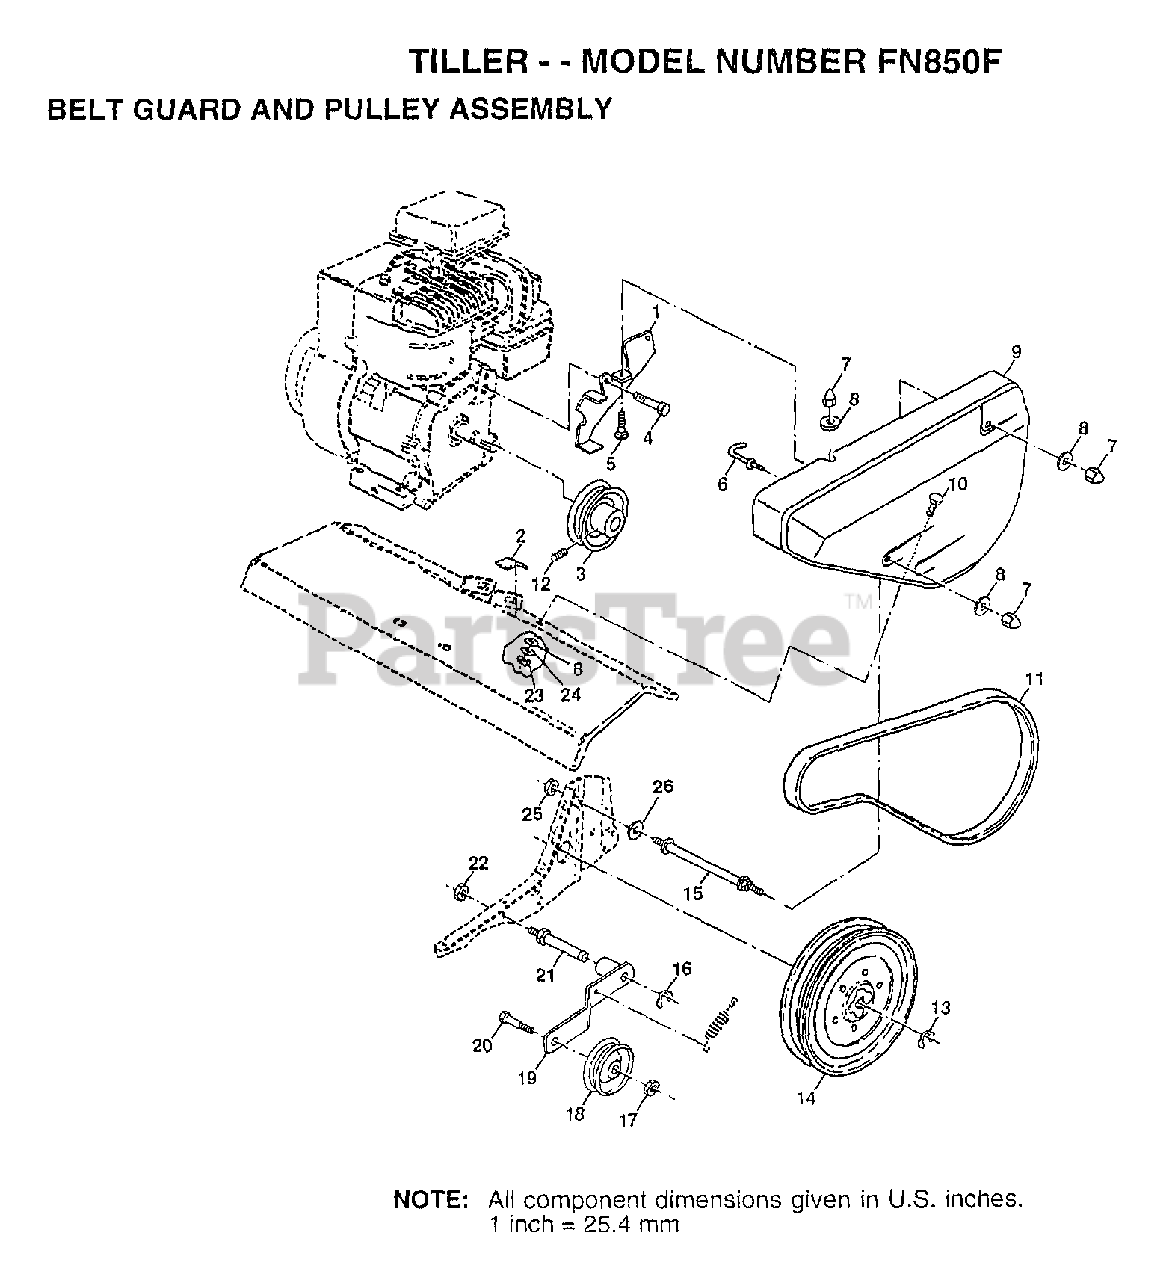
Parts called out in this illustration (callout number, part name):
1	BRKT GUARD BELT
2	PAD IDLER TI
3	ENGINE PULLEY
4	BOLT.HEX.HEAD
5	BOLT
7	NUT-CAP TI
8	WASHER
9	"GUARD, BELT"
10	BOLT T
11	V BELT STD
12	SET SCREW
14	SHEAVE.TRANS
15	BOLT TI
16	KLIP RING TI
17	NUT
18	"PULLEY,IDLER"
19	"ARM, IDLER"
21	SHAFT IDLER TI
22	JAM NUT TI
24	LOCKWASHER
25	NUT
26	WASHER
